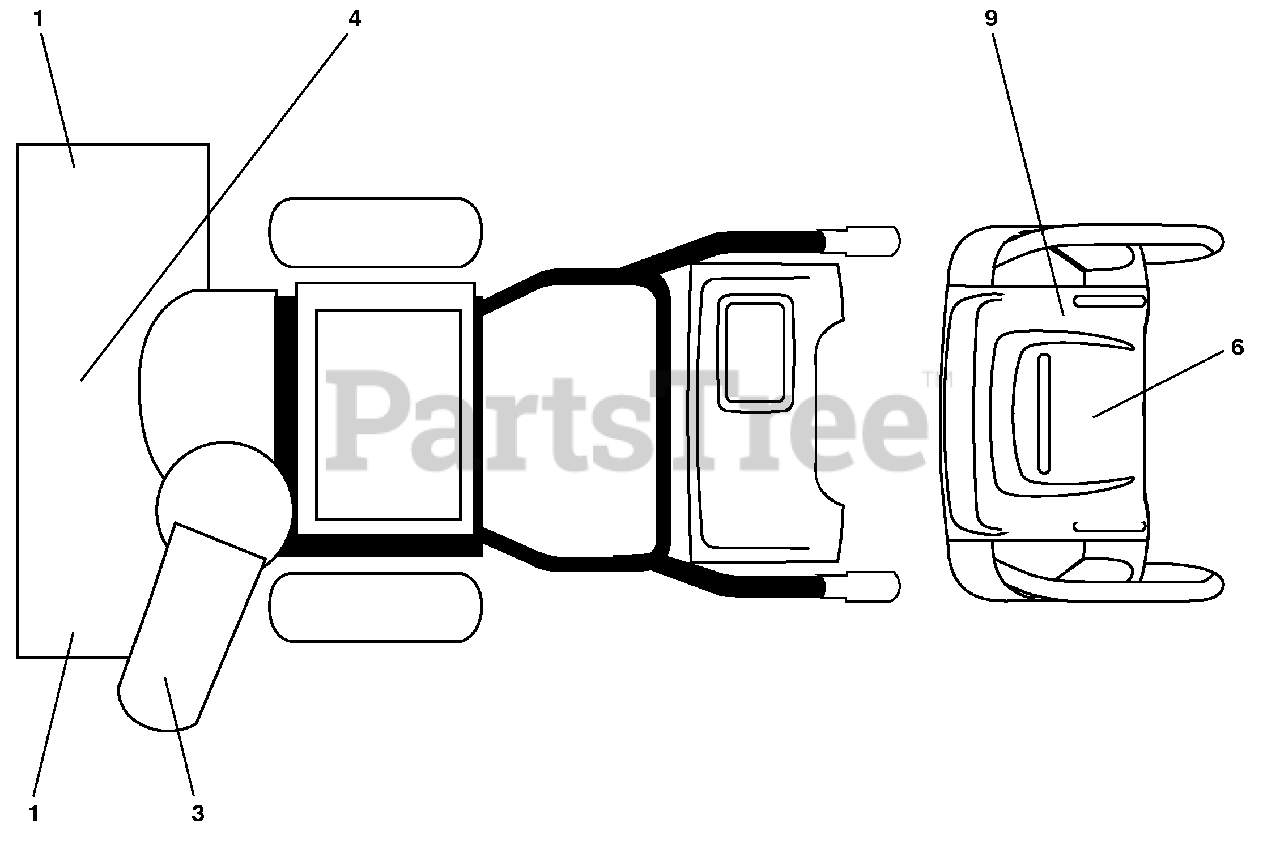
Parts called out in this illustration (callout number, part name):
1	DECAL, DANGER
3	DECAL, DANGER, DEFLECTOR
4	DECAL, DANGER
6	DECAL, INSTRUCTION
7	DECAL, CONS. LT WO/LEV/PWRST
9	DECAL, CONS. RT SPD/LEV/PWRST
9	OWNER'S MANUAL, ENGLISH
9	OWNER'S MANUAL, FRENCH
